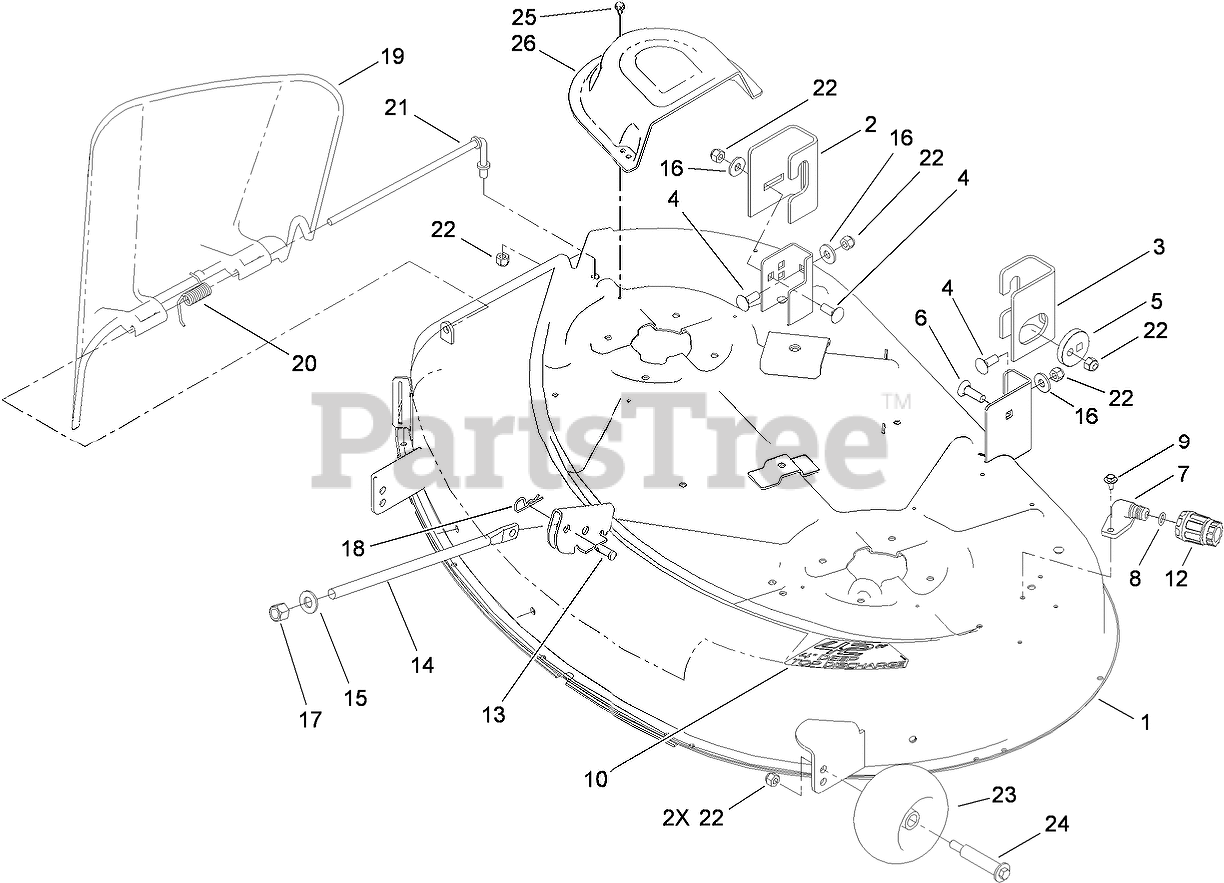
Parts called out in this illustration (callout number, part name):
1	42 INCH DECK AND DECAL ASM
2	BRACKET-HANGER, RIGHT REAR
3	BRACKET-HANGER, LEFT REAR
4	BOLT-CARR
5	ECCENTRIC
6	SCREW-CARR
7	FITTING-WASHOUT
8	O-RING
9	SCREW-HHFTF
12	CONNECTOR-HOSE
13	PIN-CLEVIS
14	ROD-LIFT
15	WASHER-THRUST
16	WASHER-HARDENED
17	NUT-LOCK, NI
18	PIN-HAIR
19	DEFLECTOR
20	SPRING-TORSION
21	ROD-PIVOT
22	NUT-LOCK, NI
23	ROLLER-SCALP, ANTI
24	BOLT-SHOULDER
25	SCREW-HWHTF
26	COVER-BELT
